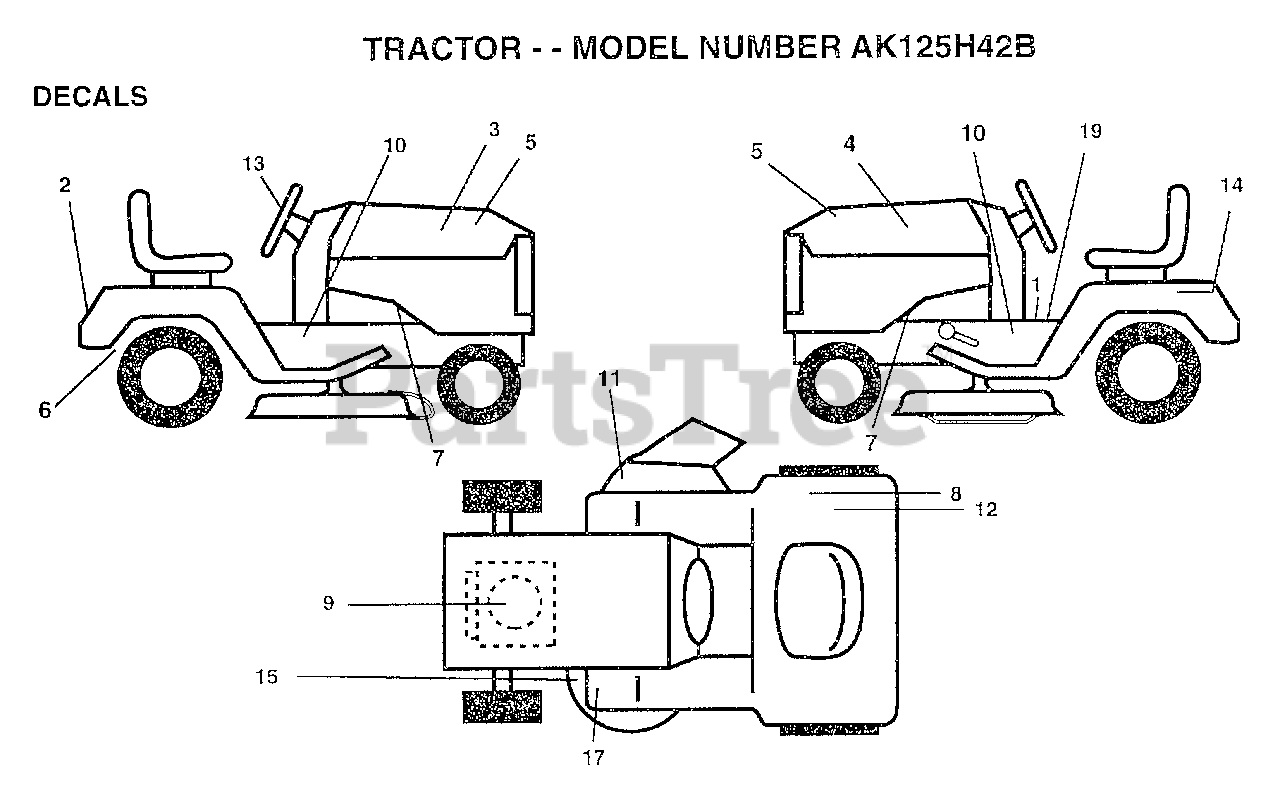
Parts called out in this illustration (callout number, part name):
1	DECAL.READ.O.MANU
2	FENDER DECAL
3	DECAL HOOD RH
4	DECAL HOOD LH
6	DECAL.DRAWBAR.LDL
7	"DECAL CHASSIS,HOT"
8	DECAL.EURO.ST.CE.
10	DECAL CHAS 42 HYD
11	DECAL.DANGER.CUTF
13	"DECAL,STR WHL"
14	DECAL.BATRY.3-3908
15	"DECAL-SCHEM,BELT"
17	DECAL-BRAKE/CLUTC
19	DECAL BRAK PARK
